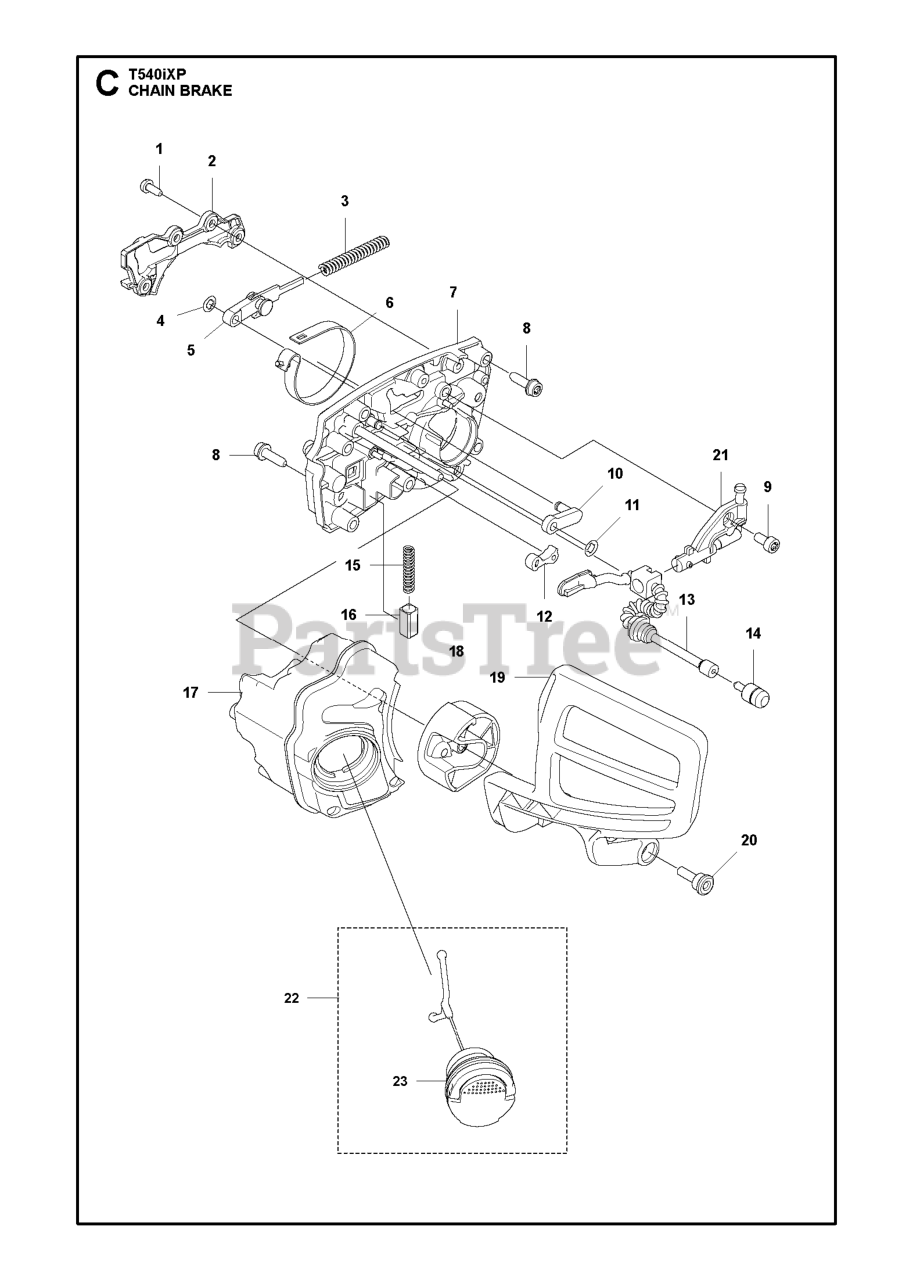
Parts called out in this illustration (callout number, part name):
2	Covers
4	Washers
5	Joints
6	BRAKE BAND
7	CLUTCH COVER ASSY
9	SCREW MC6S 5X10
10	Drive Links
11	Washers
14	OIL PLUMMET
15	LOCK SPRING
18	Hand Guard
19	Hand Guard
21	OIL PUMP ASSY
22	TANK CAP ASSY
